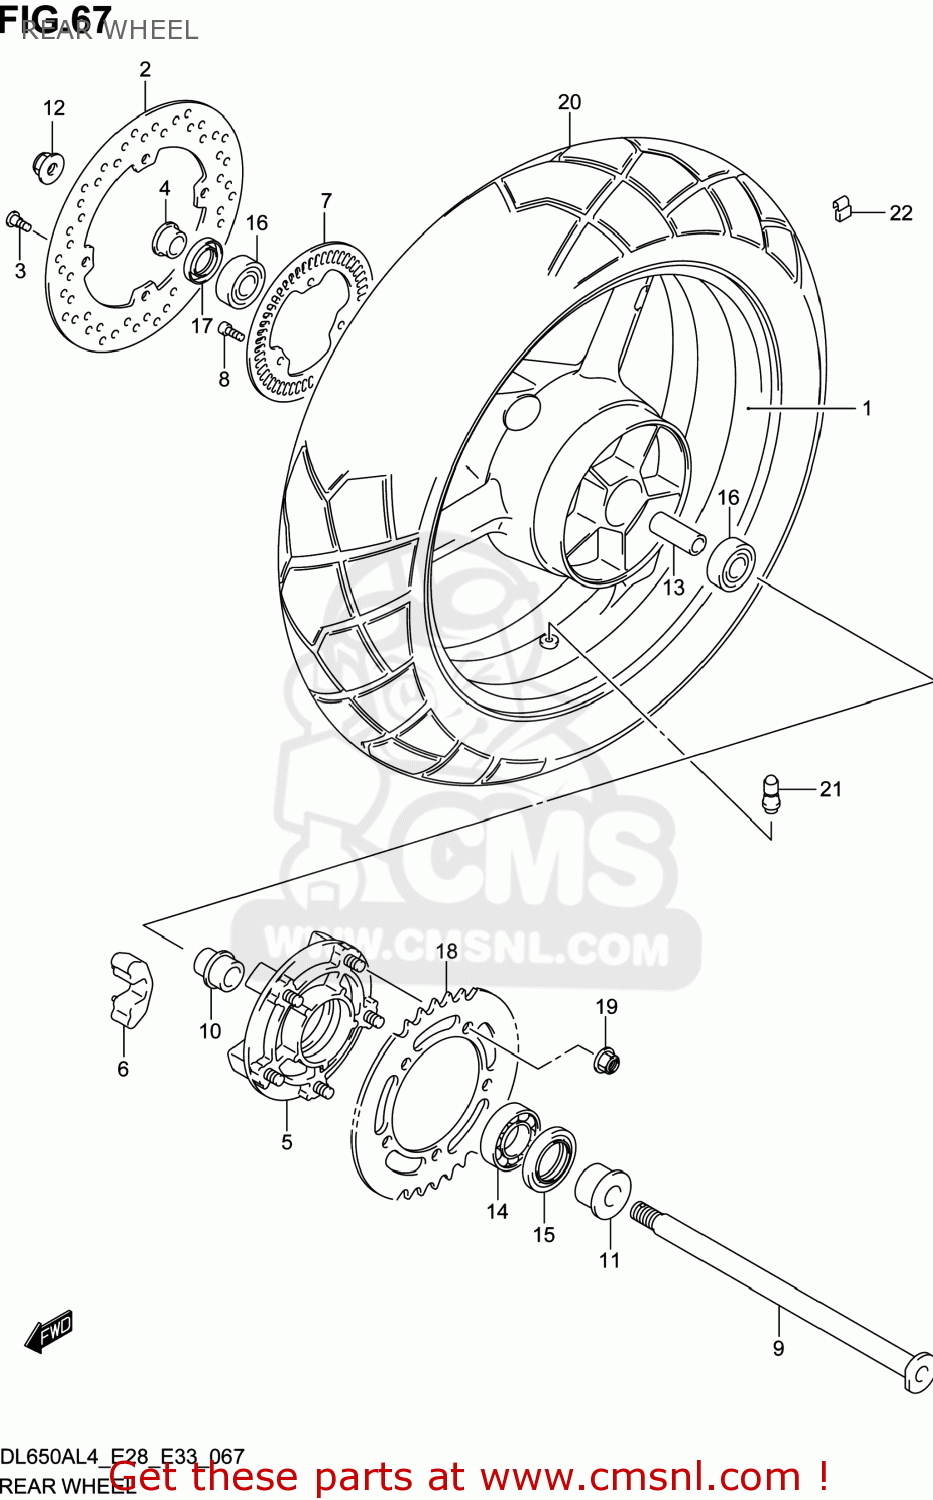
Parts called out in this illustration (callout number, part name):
1	WHEEL,RR(17M/CXMT4.00)
2	DISC,RR BRAKE
3	BOLT(8X21)
4	SPACER,RR AXLE,R
5	DRUM,RR SPROCKET
6	ABSORBER,RR HUB SHOCK
7	RING,SPEED SENSOR FR(50T)
8	BOLT
9	AXLE,RR
10	RETAINER,RR SPROCKET DRUM
11	SPACER,RR AXLE,L
12	NUT
13	SPACER(20.8X27.2X124)
14	BEARING(32X65X17)
15	SEAL,OIL(39X65X7)
16	BEARING
17	SEAL,OIL(28X47X7)
18	SPROCKET,RR(47T-525)
19	NUT
20	TIRE,REAR,150/
21	VALVE ASSY,WHEEL RIM(TR412)
22	WEIGHT,WHEEL BALANCE 10G
